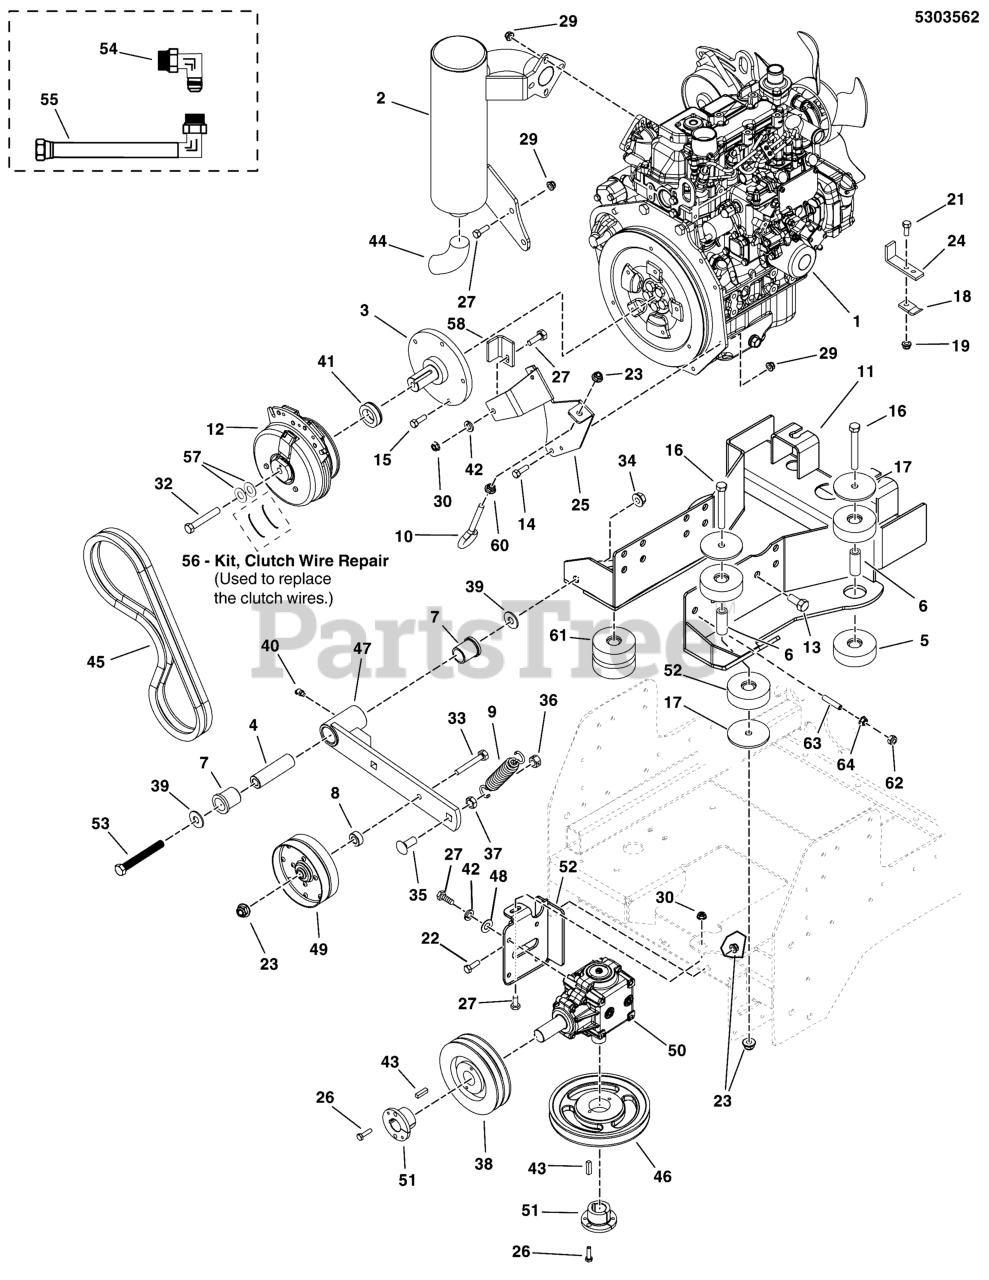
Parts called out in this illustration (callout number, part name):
1	ENGINE, YANMAR
2	MUFFLER, YANMAR
3	SHAFT, STUB, YANMAR, FLYWHEEL PLATE
4	SPACER, .52 X 1.00 X 3.50
5	ISO MOUNT, 215 LBS, YELLOW
6	SPACER, .38 X .62 X 1.62
7	BUSHING, FLANGE
8	SPACER, .39 X .75 X .38
9	SPRING-EXT 1.03OD X 6.935LG X .120WR BLK
10	EYE BOLT, 3/8-16 X 6.88, 3THRD, 1EYE
11	WELD, ENGINE MOUNT, IS2500 - RED
12	CLUTCH, WARNER ELECTRIC, IS2500Z
13	BOLT, M10-1.5 X 16MM GD8.8
14	BOLT, M8-1.25 X 20MM GD8.8
15	BOLT, M8-1.25 X 25MM GD8.8
16	BOLT, 3/8-16 X 3" GD5 CZ
17	WASHER, .39 X 2.50 X .125
18	CLAMP, CONDUIT
19	NUT, #10-24 HEX NYLON LOCK
21	SCREW, #10-24 X 3/4 ROUND PHILLIPS
22	BOLT, Carriage, 3/8-16 X 1
23	NUT, 3/8-16 HEX NYLOCK FLANGE
24	BRACKET, THROTTLE CABLE - RED
25	ANCHOR, CLUTCH - RED
26	BOLT, 1/4-20 X 1" GD5 CZ
27	BOLT, 5/16-18 X 1 GD5 YZ
28	SAFETY WALK, 4.50 X 3.50
29	NUT, M8-1.25 SERR. FLANGE, CZ
30	NUT, 5/16-18 HEX NYLOCK FLANGE
31	NUT, 5/16-18 HEX SERRATED FLANGE (SMALL)
32	BOLT, CRANKSHAFT, 7/16X2-3/4, PATCH YZ
33	BOLT, 3/8-16 X 2-1/4" GD5 CZ
34	NUT, Hex Flange, Nylock, 1/2-13
35	BOLT, CARRIAGE 1/2-13 X 1-1/4 GD.5
36	NUT, 1/2-13 HEX SIDE LOCK
37	NUT, 1/2-13 HEX JAM
38	PULLEY, 5.75 OD X 2 GROOVE, SPECIAL
39	WASHER, 1/2 USS
40	GREASE FITTING, 45 DEGREE
41	SPACER, 1.13 X 1.75 X .50
42	WASHER, 5/16 LOCK CZ
43	KEY, 1/4 SQ X 1
44	TAIL PIPE, 1-1/2", 90 DEGREE (SV)
45	BELT, A-SEC, 40.084" EL, MATCHED SET
46	PULLEY, 7.75"OD, B SEC, DEEP GROOVE, CI
46	PULLEY, B-SEC, 7.032" DIA. OB. PHOSPHATE
47	WELD, IDLER ARM - BLK
48	WASHER, 5/16" SAE
49	PULLEY, IDLER, DOUBLE FLGED, 4IN
50	GEARBOX, RIGHT ANGLE, 1:1
51	BUSHING, TAPERED HUB
52	ISO MOUNT, 490 LBS, GREEN
53	BOLT, 1/2-13 X 5, GD5
54	FITTING, #8JIC - M16X1.5, ELBOW
55	HOSE, OIL DRAIN
56	KIT, CLUTCH WIRE REPAIR
57	BELLEVILLE WASHER 1.1875 X .442 X .089
58	BRACKET, CLUTCH ANCHOR, IS2500 - BLK
59	WELD, GEAR BOX - RED
60	NUT, 3/8-16 HEX
61	ISO MOUNT, 360 LBS, RED
62	HEX NUT, M10-1.5 NYLON INSERT
63	SOCKET SET SCREW, M10-1.5 X 50, SS, CAP PT
64	HEX NUT, FLG, M10-1.5 SER CZ, NO SEALER
